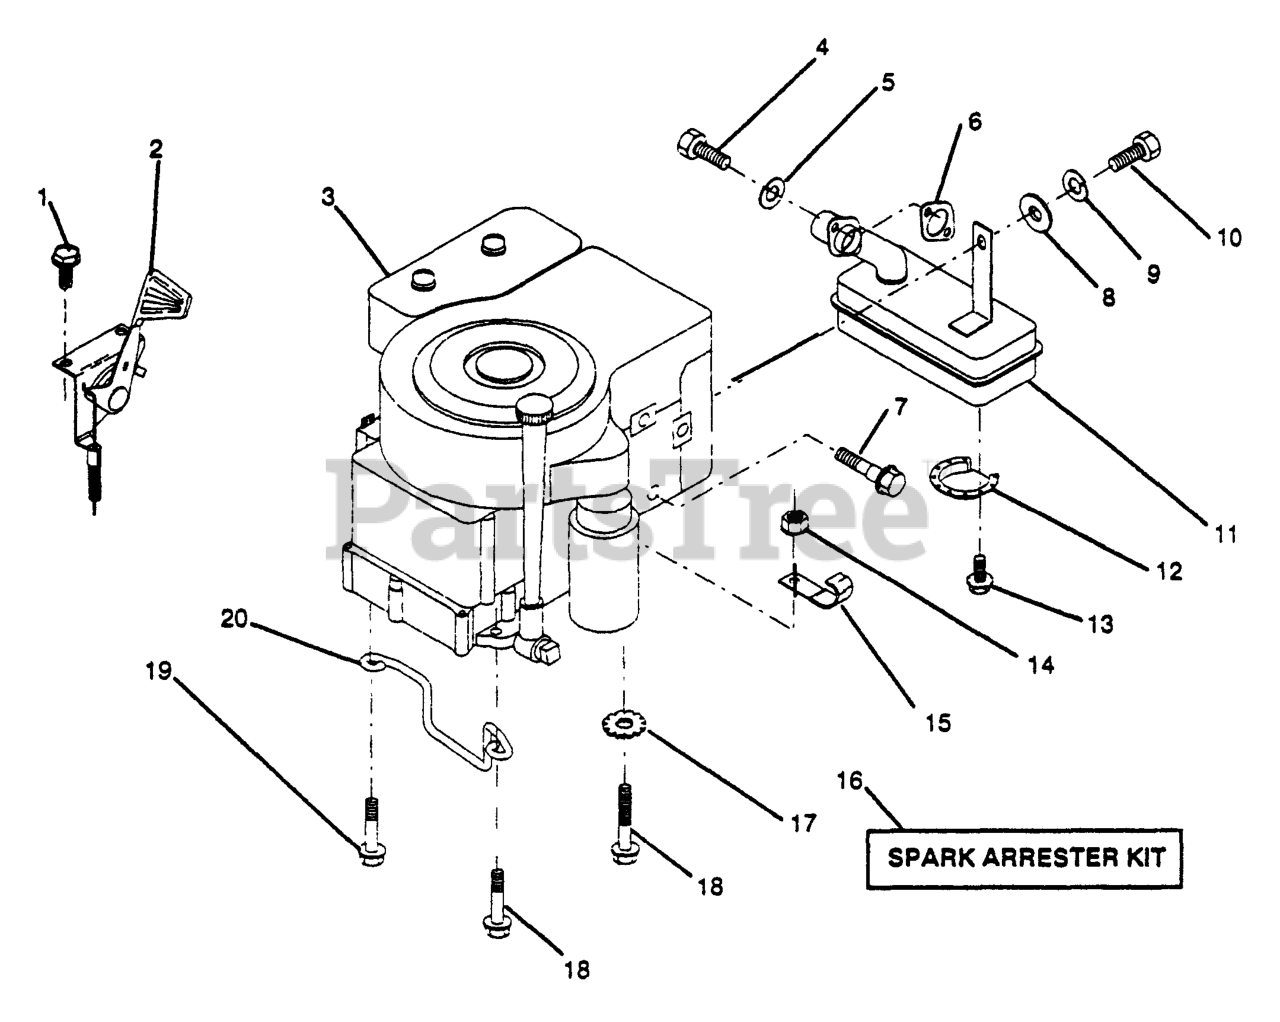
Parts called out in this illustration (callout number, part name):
1	SCREW
2	CONTROL
3	Engine, Briggs and Stratton
4	SCREW
5	WASHER.LOCK.HVY.HLCL.SPR.5/16
6	GASKET ENGINE
8	WASHER
9	LOCKWASHER
10	BOLT
11	MUFFLER
12	DEFL MUFFLER LTV
13	SCREW
15	CLIP T
16	SPARK ARREST
17	LOCKWASHER
18	Screw, Hex Wsh Hd Thdrol 3/8-16 x 2
19	SCREW LT
20	KEEPER,DR BELT GR
